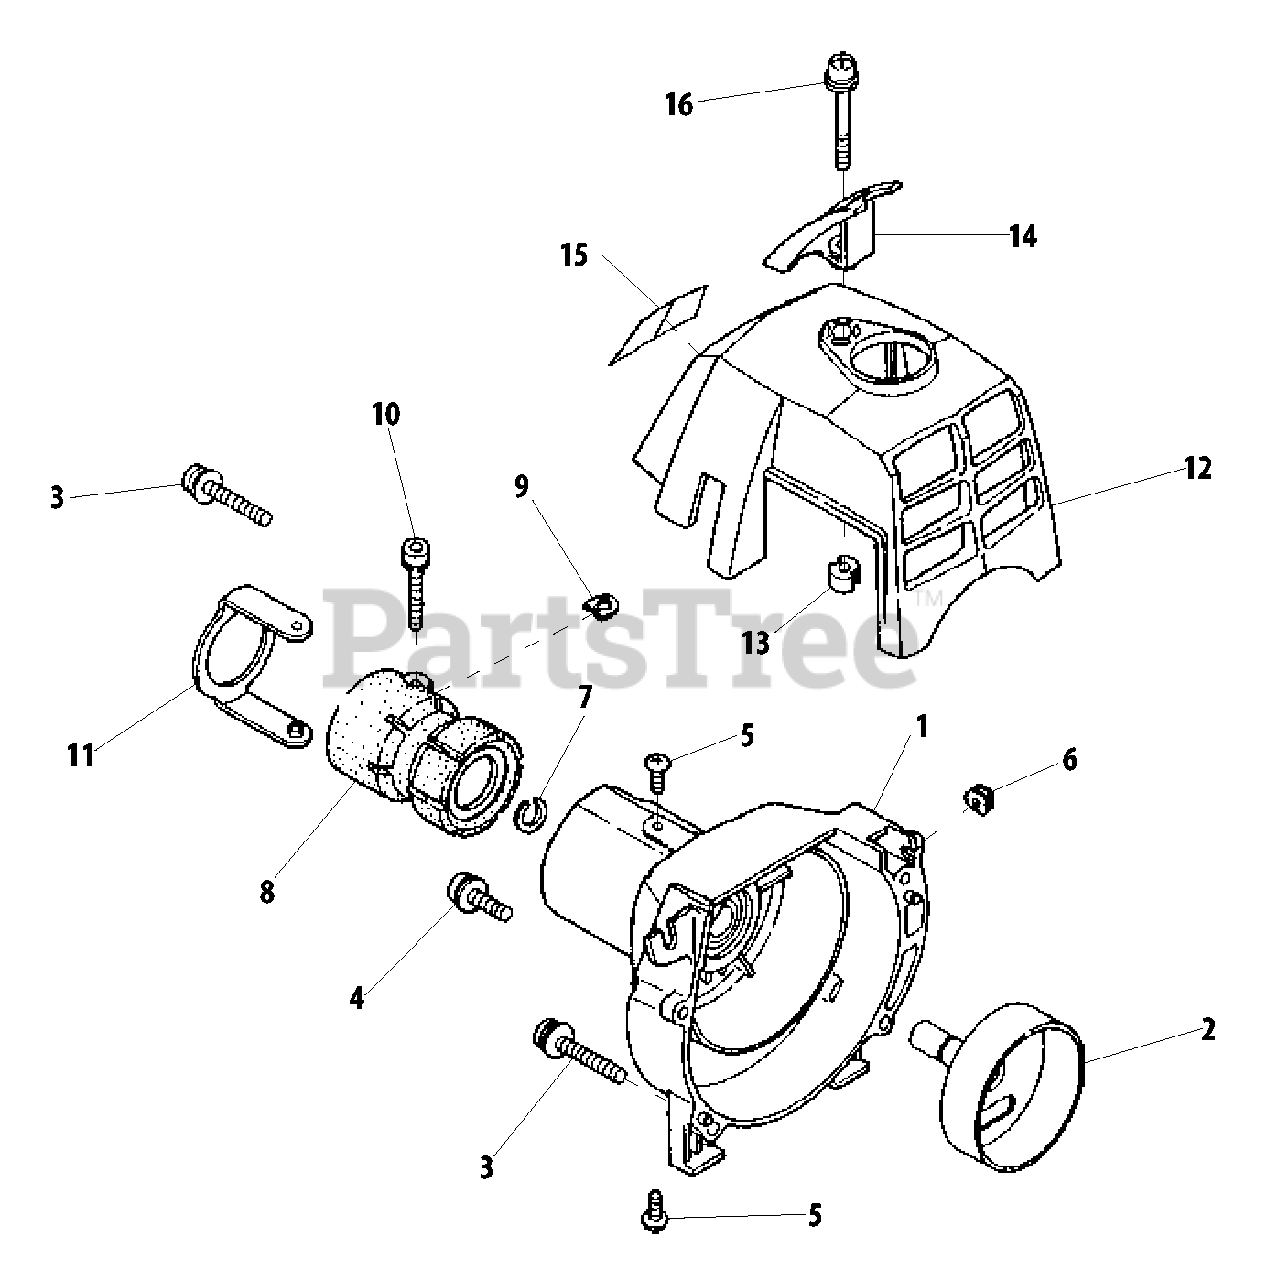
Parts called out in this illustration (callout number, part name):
1	COVER, FAN
2	DRUM, CLUTCH
3	SCREW M5×30
4	SCREW M5×16
5	SCREW, ADHESIVE M4×8
6	GROMMET, LEAD
7	RING, SNAP Ø12
8	JOINT
9	D-WASHER
10	BOLT M5×22
11	STOPPER
12	COVER, ENGINE
13	INSULATOR
14	PROTECTOR
15	LABEL, MODEL
16	SCREW
